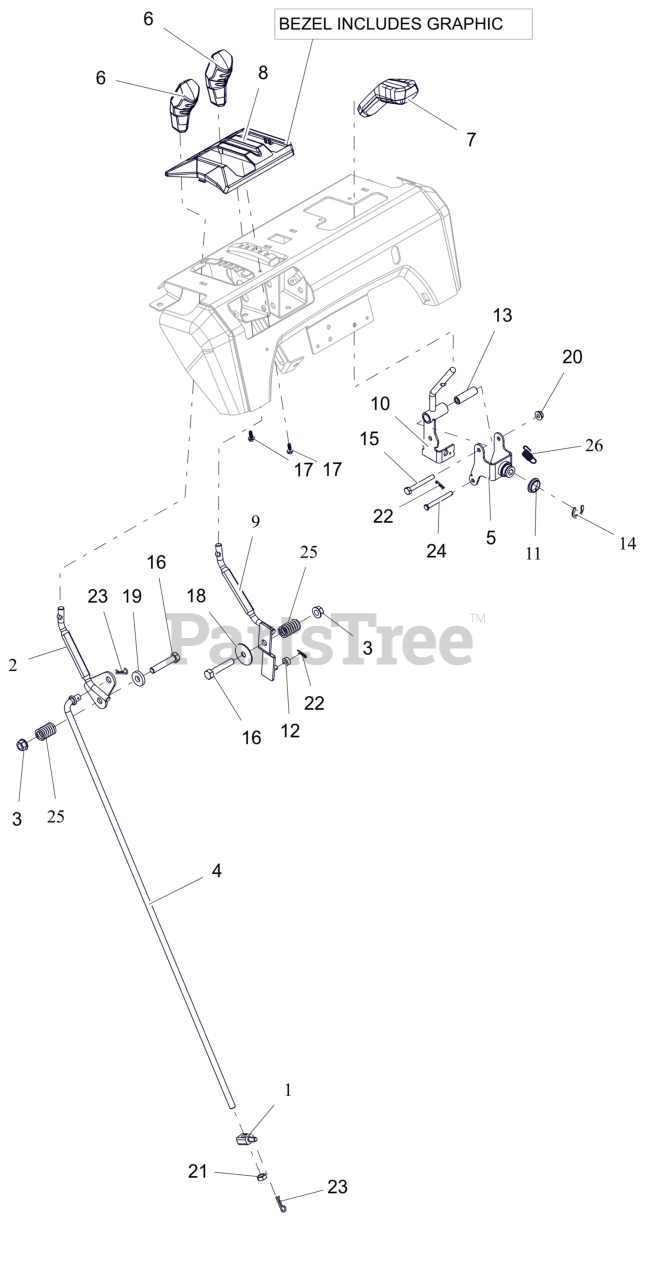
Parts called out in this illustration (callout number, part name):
1	PIVOT,SHIFT ROD .375-16(TRUNN)
2	WELDMENT,LG DASH SPEED CONTROL
3	NUT-LK-TOP-FLG .38-16 ZC120
4	ROD, SHIFT - LARGE DASH DELUXE
5	WELDMENT, CONTROL BRACKET
6	KNOB- ADJUST - SPEED/CHUTE CAP
7	KNOB- QUICK TURN
8	BEZEL- SHIFT - FRICTION
9	WELDMENT,LG DASH DEFL CONTROL
10	WELDMENT, CONTROL LEVER
11	BUSHING, POLYLINER-.75 SNAPIN
12	BSHG-SLV .265X.500X.219
13	BSHG, SLV .265X.505X1.665
14	E-RING .750X.050
15	BLT,HEX .25-20X2.25 G5 ZCC
16	BLT,HEX .38-16X2.00 G5 ZCC
17	SCR, PLASTIC #10X.50
18	WSHR,FLT .380X1.50X.062 ZCC
19	WSHR, FLT .406X1.00X.188 ZCC
20	NUT-LK-CTR-FLG .25-20 ZC120
21	NUT-JAM .375-16 G2 ZCC
22	PIN, HAIR #178 .06X.77 ZCC
23	PIN, HAIR #213 .08X1.19 ZCC
24	PIN, CLEVIS - .25 X 2.25 ZCC
25	SG-COMP .125X.781X1.250
26	SPRING-EXT .047X.438X1.45
